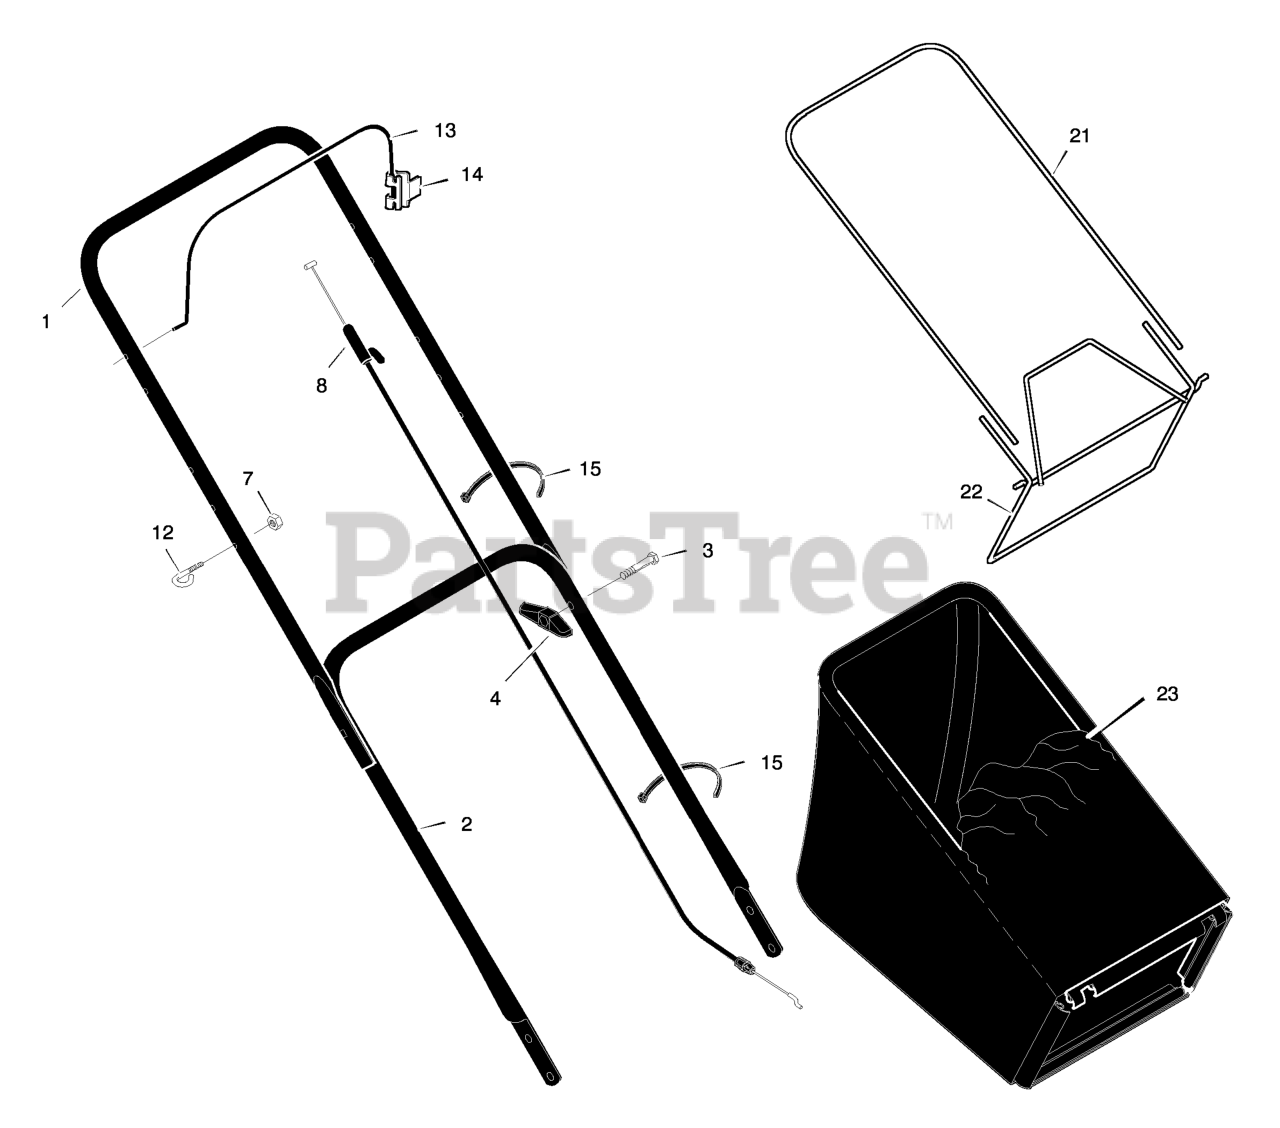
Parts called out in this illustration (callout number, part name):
1	Handle, Upper
2	Handle, Lower
4	Knob, Plastic
7	Locknut
8	Engine Stop Cable
12	Guide, Rope
13	Engine Stop Lever
14	Bracket, Stop Lever
15	Fastener, Cable
21	Frame, Top
22	Frame Assembly
23	Bag, Cloth
